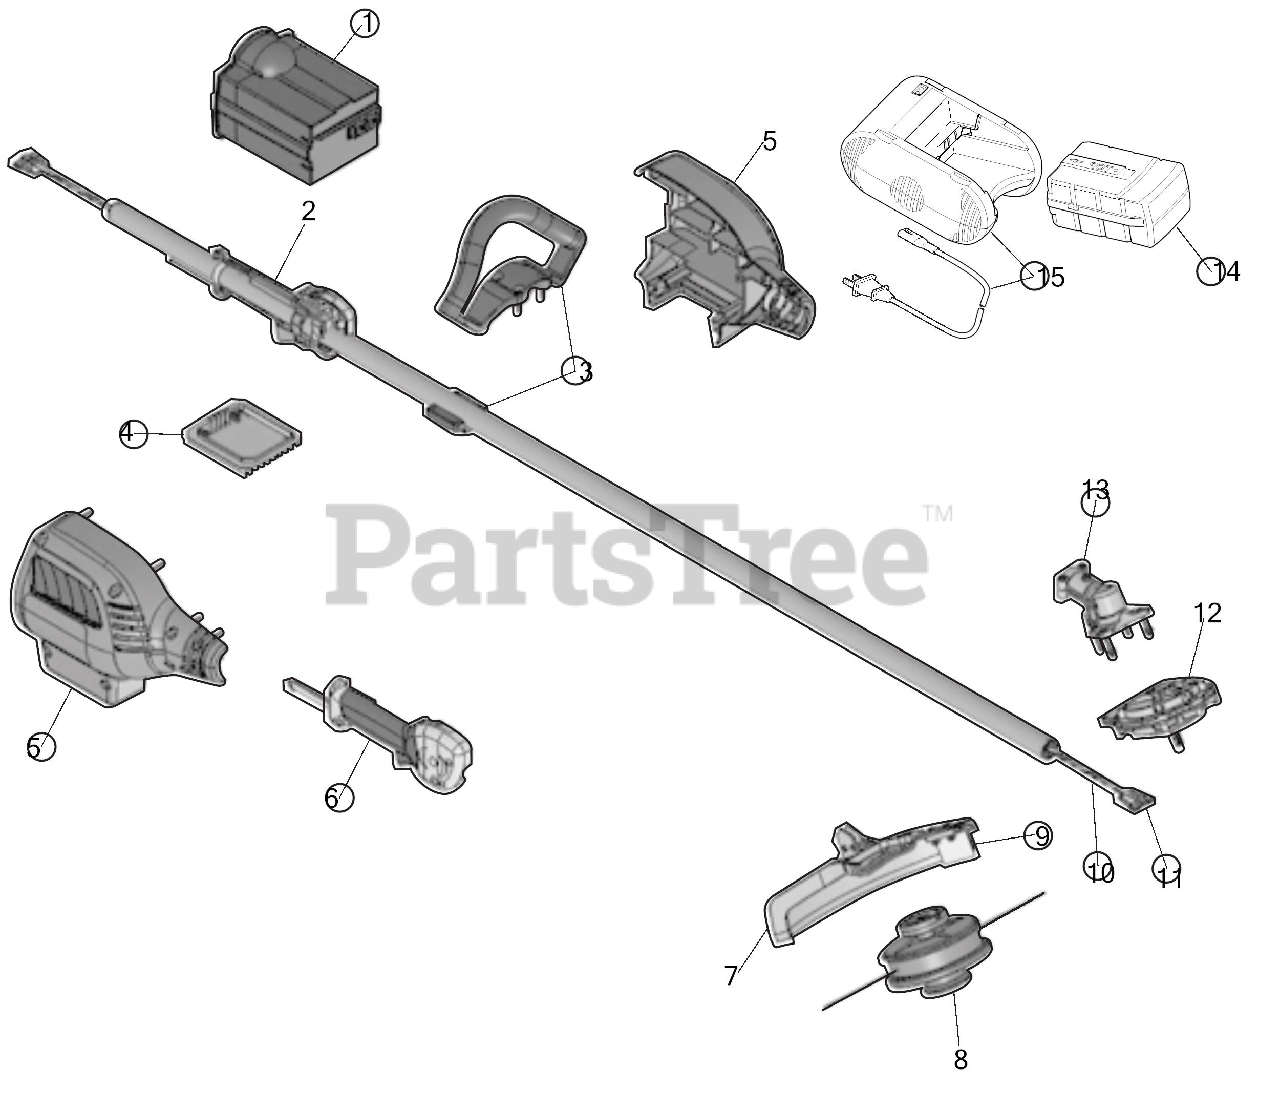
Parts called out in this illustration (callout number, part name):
1	PWR:SLV ASSEMBLY CGT400 CDU400 CORE
2	BOOM ASSEMBLY W/WIRES CGT400 CORE
3	HANDLE ASSEMBLY CORE
4	CONTROLER CGT400 CORE
5	PWR:HOUSING ASSEMBLY CGT400 CDU400 CORE
6	GRIP ASSEMBLY KIT CGT400 CORE
7	GUARD ASSEMBLY W/BLD CORE
8	BUMPHEAD ASSEMBLY COMP CORE
9	BLADE ASSEMBLY CORE
10	HARNESS PHS WIRE CGT400 CORE
11	HARNESS HALL WIRE CGT400 CORE
12	MOTOR ASSEMBLY CGT400 CORE
13	YOKE ASSEMBLY CGT400 CORE
14	CORE BATTERY 18.5V
15	CHARGER 21V
